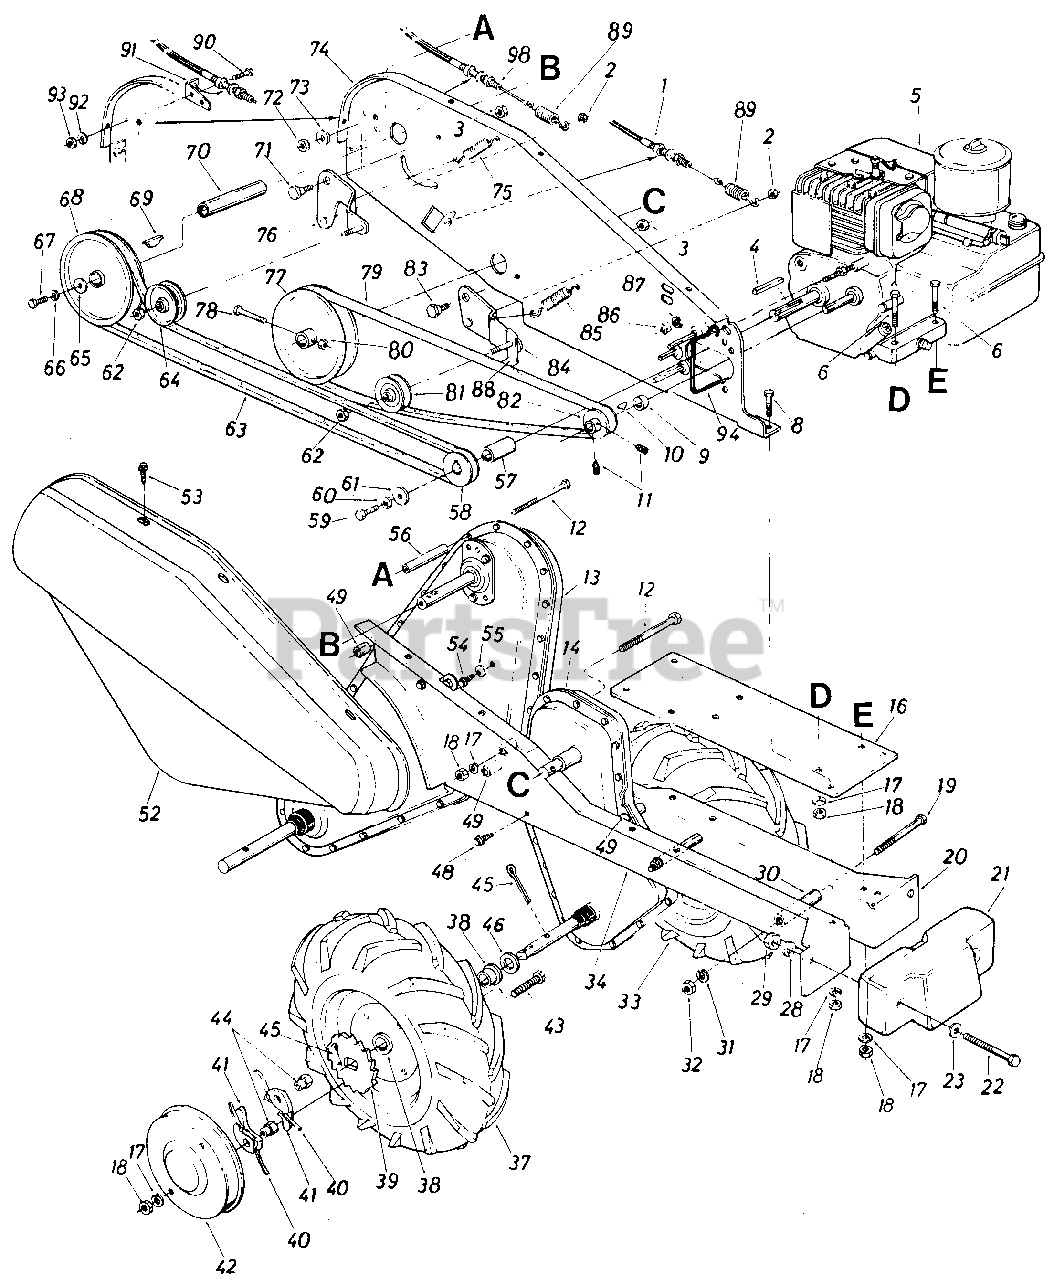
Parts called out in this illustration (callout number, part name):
1	CONTROL-CLUTCH
2	NUT-HEX CENTER L-1/4-20
3	NUT-HEX CENTER L-JAM
4	KEY-SQ 3/16 X .75
6	SCREW-HEX 5/16-18 X 1.50
8	SCREW-HEX 5/16-18 X .75
10	KEY-HI-PRO #5-1/8X5/8 DIA
11	SCREW-SET 1/4-28 X .25
12	SCREW-HEX 5/16-18 X 3.00
18	NUT-HEX 5/16-18
19	SCREW-HEX 3/8-24 X 3.0 LG
22	SCREW-HEX 1/2-13 X 4.0
23	WASHER-FL
28	WASHER-LOCK-1/2
29	NUT-HEX 1/2-13
31	WASHER-LOCK-3/8
32	NUT-HEX 3/8-24
33	WHEEL ASSY W/TIRE-LH
38	BEARING-FLANGE
40	SPRING-NYLON
41	PAWL
42	COVER-WHEEL
43	SCREW-HEX 5/16-24 X 1.25
44	NUT-HEX 5/16-18 SPEC
45	PIN-COTTER-1/8 DIA X 1.25
46	WASHER-FL-.885 ID X 1.37 OD X .060
48	SCREW-HEX WASH SF TAPP
52	COVER-BELT
53	SCREW-HEX WASH SF TAPP
54	SCREW-TAP 1/4-20 X .38
55	WASHER-SPRING BELL
59	SCREW-HEX SPECIAL 5/16-24X1.0
60	WASHER-LOCK-5/16
61	WASHER-5/16 X 1.25 X 1.27
62	NUT-HEX INS L-3/8-24
63	BELT-V 1/2 X 54
64	PULLEY-IDLER
65	WASHER-FL
66	WASHER-FL .630 X 1.00 X .020
67	SCREW-HEX 1/4-28 X .75
68	PULLEY
69	KEY-3/16 X 5/8
71	SCREW-SHLD
72	NUT-HEX 5/16-18
73	WASHER-LOCK-5/16
74	PLATE ASSY-SIDE
75	SPRING-EXTENSION
76	BRACKET ASSY-TINE
78	SCREW-HEX
79	BELT-V 1/2 X 43
80	NUT-HEX CENTER L-1/4-28
81	PULLEY-V-BELT IDLER
83	SCREW-SHLD .500 DIA X .170
84	BRACKET ASSY-WHL
85	SPRING-EXTENSION
86	NUT-HEX 1/4-20
87	WASHER-SPRING BELL
88	BRACKET-BELT GUARD
89	SPRING-EXTENSION
90	SCREW-HEX 5/16-18 X .75
91	BRACKET-CLUTCH
92	WASHER-LOCK-5/16
93	NUT-HEX 5/16-18
94	GUARD-BELT
